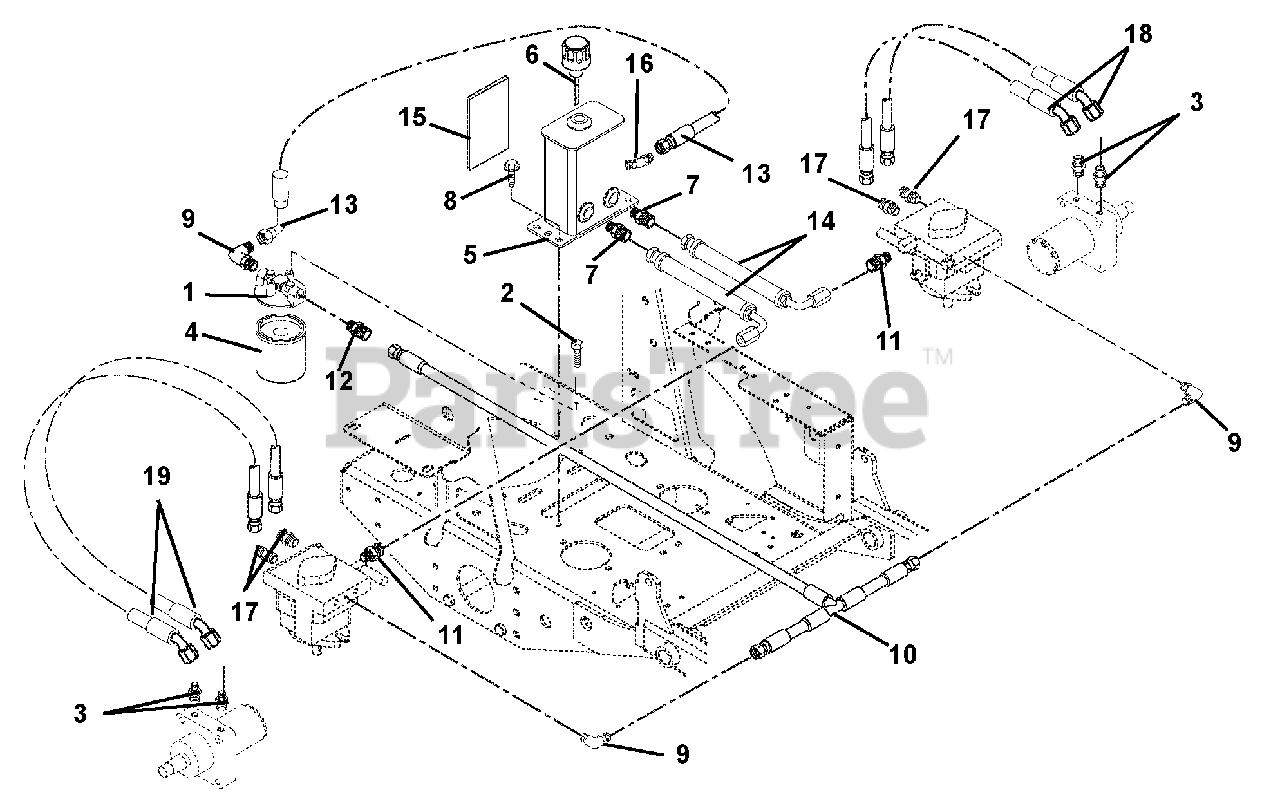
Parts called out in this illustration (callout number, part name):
1	HEAD, FILTER
2	BLT-HEX .25-20X.50 GR5 EPOXY
3	FTG, HYD STR M10O-M8F
4	ELEMENT, OIL FILTER
5	WMT,FORMED HYD.TANK-3 PORT
6	BREATHER, DIPSTICK
7	FTG, HYD STR M8O-M4F
8	@SCR-TAP .38-16X.50 HWH TR YWZ
9	FTG. HYD. 90 EL M8F-M8O
10	HOSE, .50 TO .38 TEE ASSEMBLY
11	FITTING, HYD (4-6 F5OLO)
12	FITTING, HYD (6 F5OLO)
13	HOSE, HYD..50-11-OK F8F0-F8F9
14	HOSE, HYD .25-3-0K F4F0-F4F9
15	SHEILD, HEAT 5.50X4.50
16	FTG, HYD 45DEG M6F-M8O
17	ADPTR,FACE SEAL 8X8 1/2 O-RING
18	HOSE,HYD .50-11-3K F8O0-F8O4
19	HOSE,HYD .50-12-3K F8O0-F8O4
